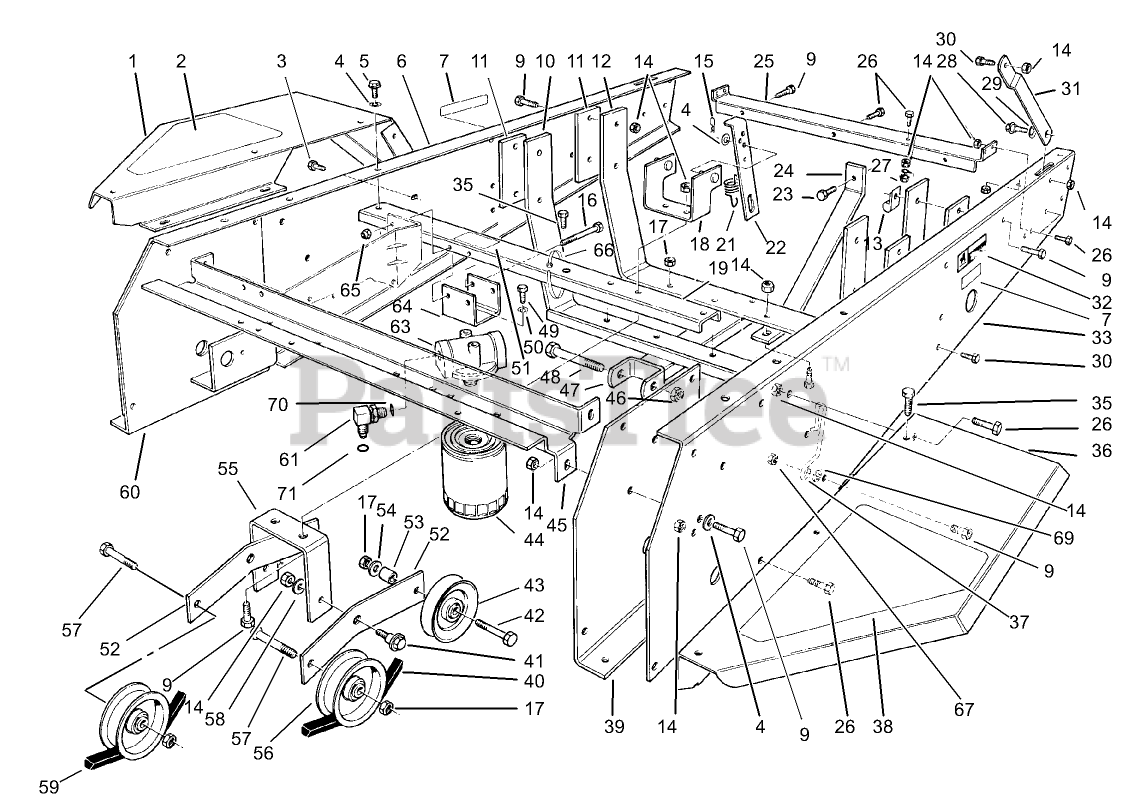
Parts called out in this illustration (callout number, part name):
1	Fender R.H
2	RH FENDER PAD
3	SCREW-HHF
4	WASHER-PLAIN
5	SCREW-HWHTF
6	Channel-Side R.H.
7	DECAL-WARNING
9	SCREW-HH
10	Mount-Engine
11	REAR ENG PLATE
12	Mount-Engine
14	NUT-LOCK, NI
15	PIN-COTTER
16	SCREW-HH
17	NUT-LOCK, NI
18	Anchor-Spring
19	Channel-Middle
20	SCREW-HH
21	IDLER SPRING
22	IDLER ANCHOR LINK
24	Bar-Tension
25	Support-Shield
26	SCREW-HH
27	NUT-KEPS
28	SCREW-SHOULDER
29	WASHER-SPRING
30	SCREW-HH
31	Stop-Hood Lower
32	Decal-Warning
33	Channel-Side LH.
35	SCREW-HHFTF
36	Fender L.H.
37	BELT GUIDE
38	LH FENDER PAD
39	Axle Stand-LH.
40	V-BELT, JACKSHAFT
41	SCREW-SHOULDER
42	SCREW-HH
43	PULLEY
44	FILTER-OIL, TRANSMISSION
45	Channel-Front
46	NUT-LOCK
47	Mount-Cylinder
48	SCREW-HH
49	SCREW-HH
50	WASHER-LOCK
51	DECAL-OIL
52	IDLER LEVER
53	SPACER-WEIGHT
54	WASHER-FLAT
55	IDLER MT BRKT
56	PULLEY
57	SCREW-HH
58	WASHER
59	V-BELT, TRACTION
60	Axle Stand R.H.
61	FITTING-STRAIGHT
63	HEAD-FILTER
64	BRACKET - FILTER HEAD
65	NUT-LOCK, NI
66	TIE-CABLE
67	NUT-HF
69	WASHER-LOCK
70	O-RING
71	O-RING
